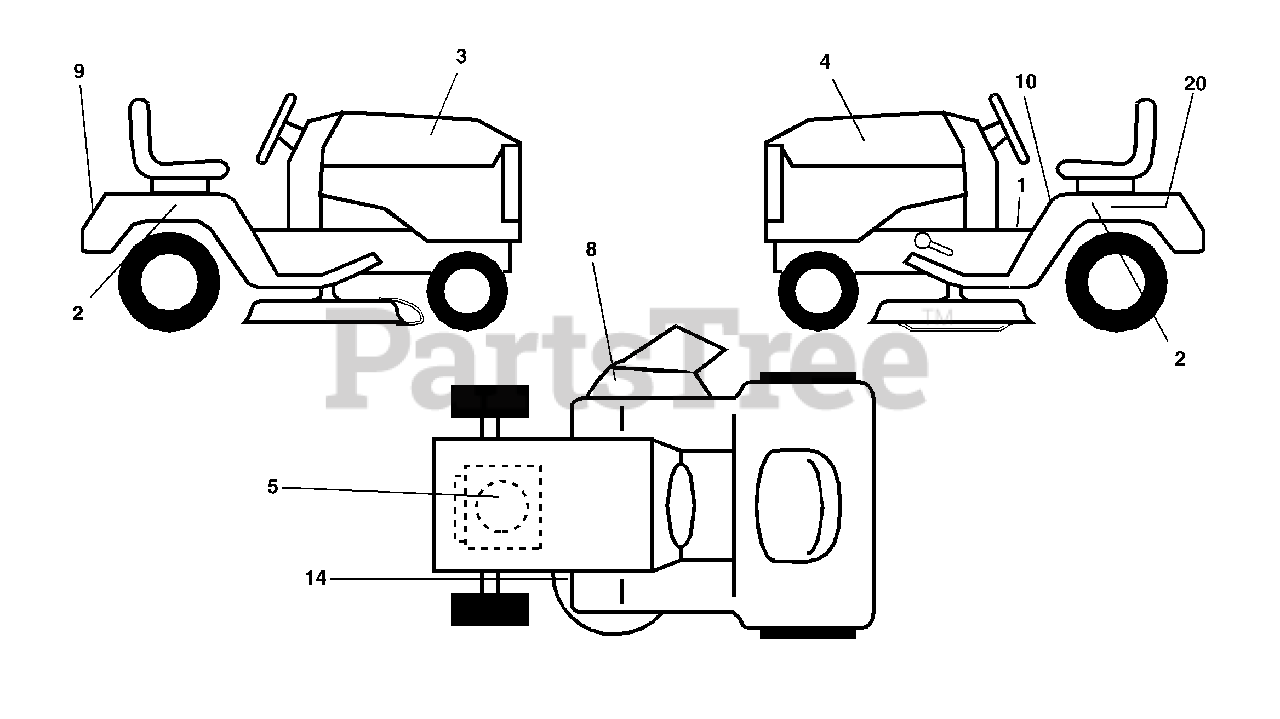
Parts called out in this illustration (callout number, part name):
1	Decal Oper Step Thru Eng/Fr
2	Decal Fender Auto Husq. Radius
3	Decal Hood RH
4	Decal Hood LH
5	Decal HP Engine
8	Decal Warning
9	Decal Fender Husq
10	Decal Fender Danger Eng/Fr
14	Decal V-Belt Schematic
20	Decal Bat Dan/Psn
